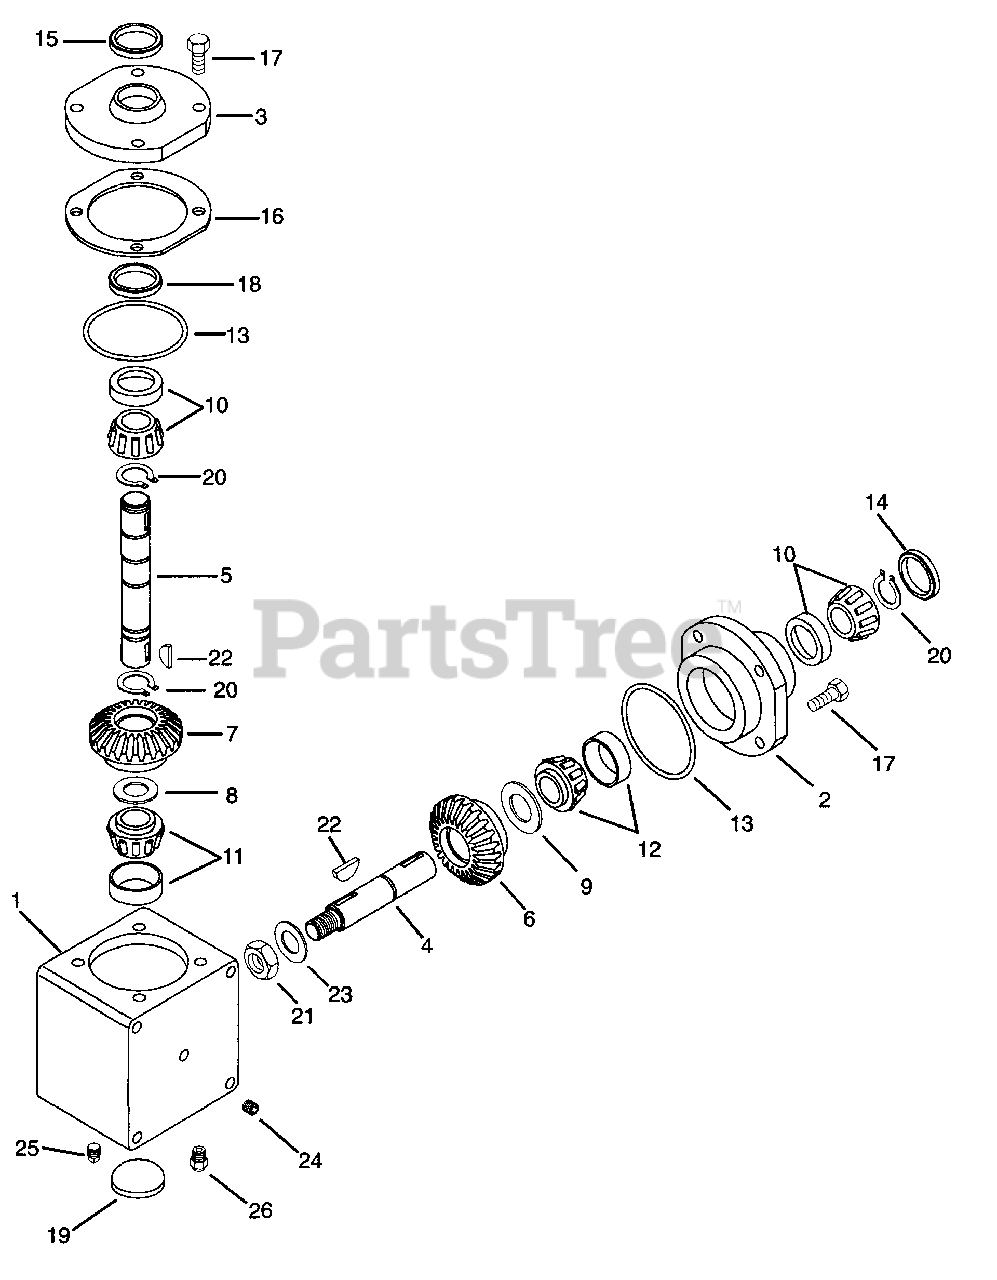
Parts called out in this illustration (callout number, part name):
1	Housing, Right Angle Drive
2	Cap, Retainer
3	Cap, Retainer
4	Shaft, Input (5.38" long)
5	Shaft, Output (7.89" long)
6	Gear, Spiral Bevel (25 teeth)
7	Gear, Spiral Bevel (26 teeth)
8	Shim (1-1/2" O.D. x 1-1/64" I.D. x .002 thick)
9	Shim (2.000" O.D. x 1.531" I.D. x .002 thick)
10	Bearing & Cup Assembly.
11	Bearing & Cup Assembly.
12	Bearing & Cup Assembly.
13	"O" Ring
14	Seal, Oil
15	Seal, Oil
16	Shim, Cap Retainer
17	Screw, Hex, HD. Sems, 5/16-18 x 1
18	Ring Load
20	Ring, Retaining
21	Jam, Nut 3/4-16
22	Key, Woodruff
23	Washer, Flat 1
24	Plug, Pipe 14-18
25	Plug, Pipe 1/8-27
26	Valve, Relief
